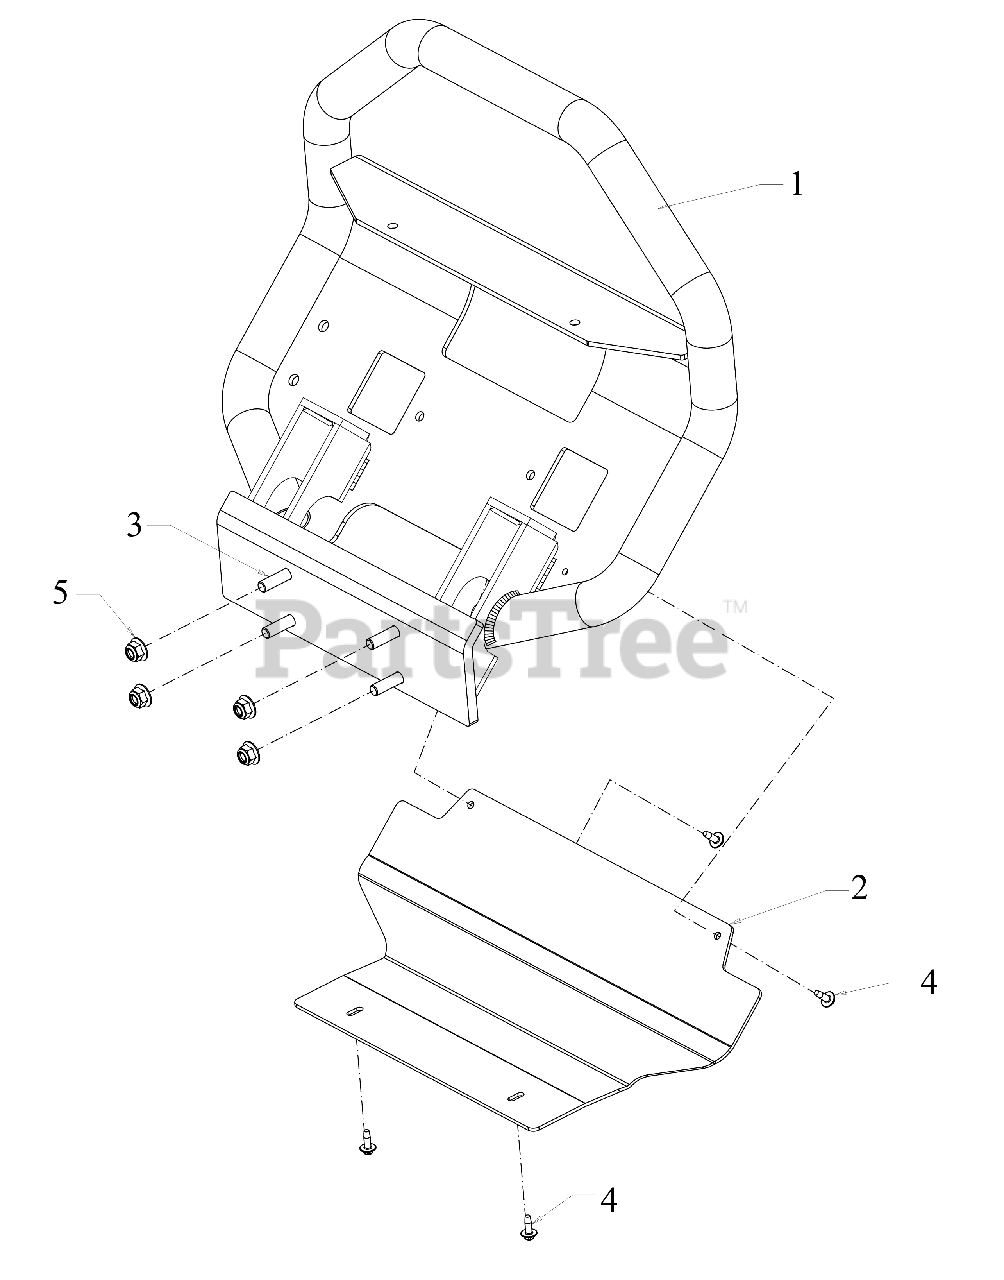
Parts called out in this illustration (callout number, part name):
3	SCREW 3/8-16 x 1.50
4	SCREW 1/4-20 X.500
5	FLANGE LOCK NUT
